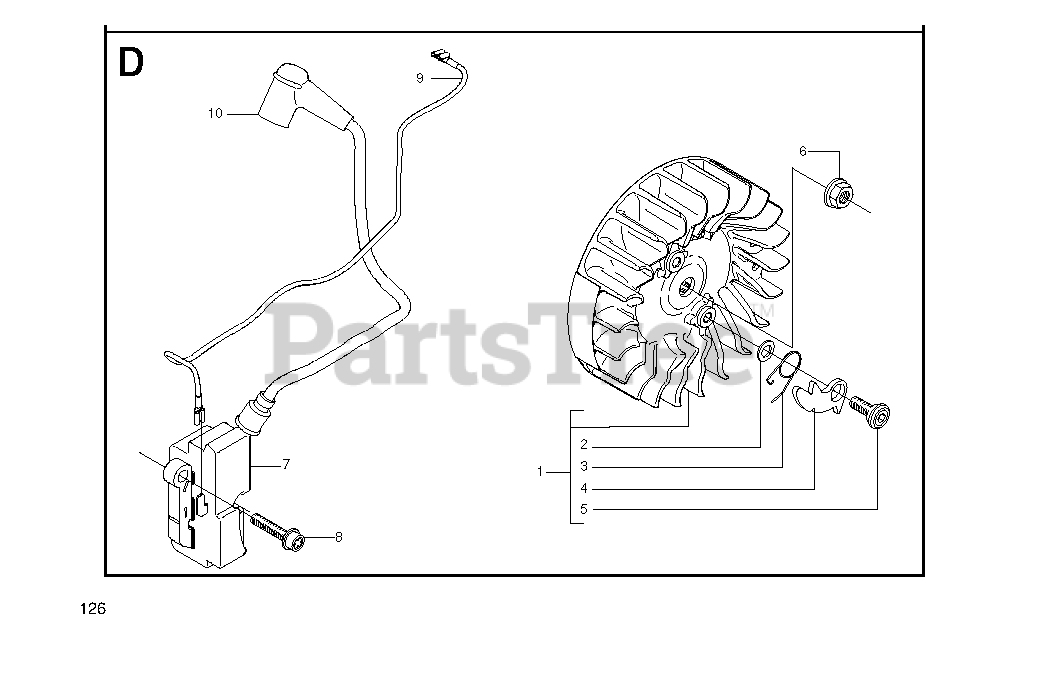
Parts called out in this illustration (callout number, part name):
1	FLYWHEEL
5	SCREW M5X14
6	NUT W/ WASHER
7	IGNITION MODULE
9	SHORTING LEAD
10	SPARK PLUG CONN. KIT
